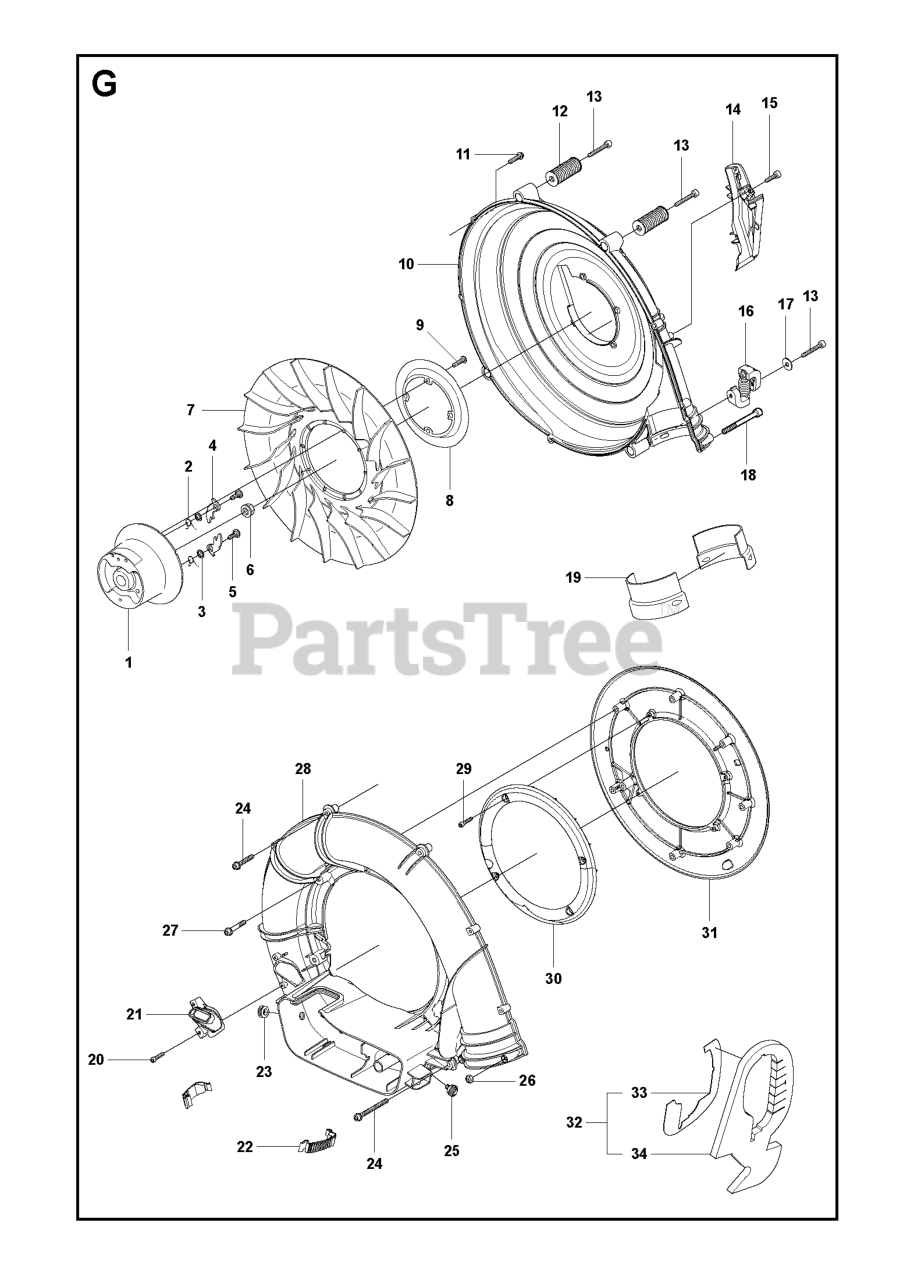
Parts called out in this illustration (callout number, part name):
5	SCREW M5X14
6	NUT W/ WASHER
14	AIR CONDUCTOR
22	BUCKLE ORANGE
33	TAPE DOUBLE-STICK
